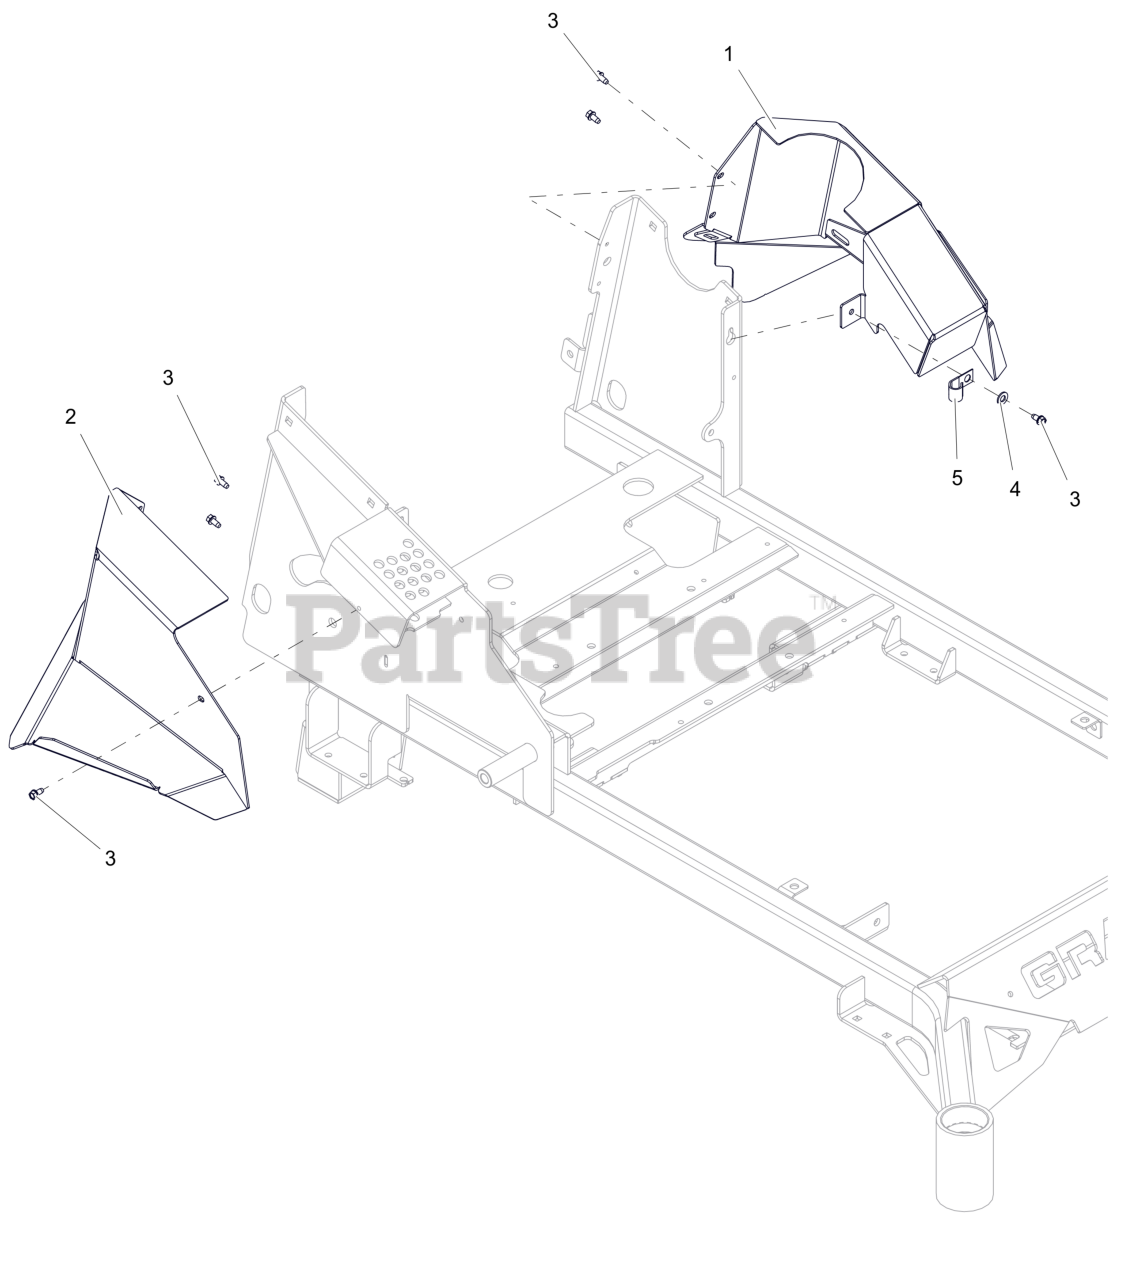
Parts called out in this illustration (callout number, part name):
1	WLDMT- LH FENDER
2	WLDMT- RH FENDER
3	SCR-TAP .25-20X.50 HWH ZCC
4	WSHR,FLT .344X.688X.065 ZCC
